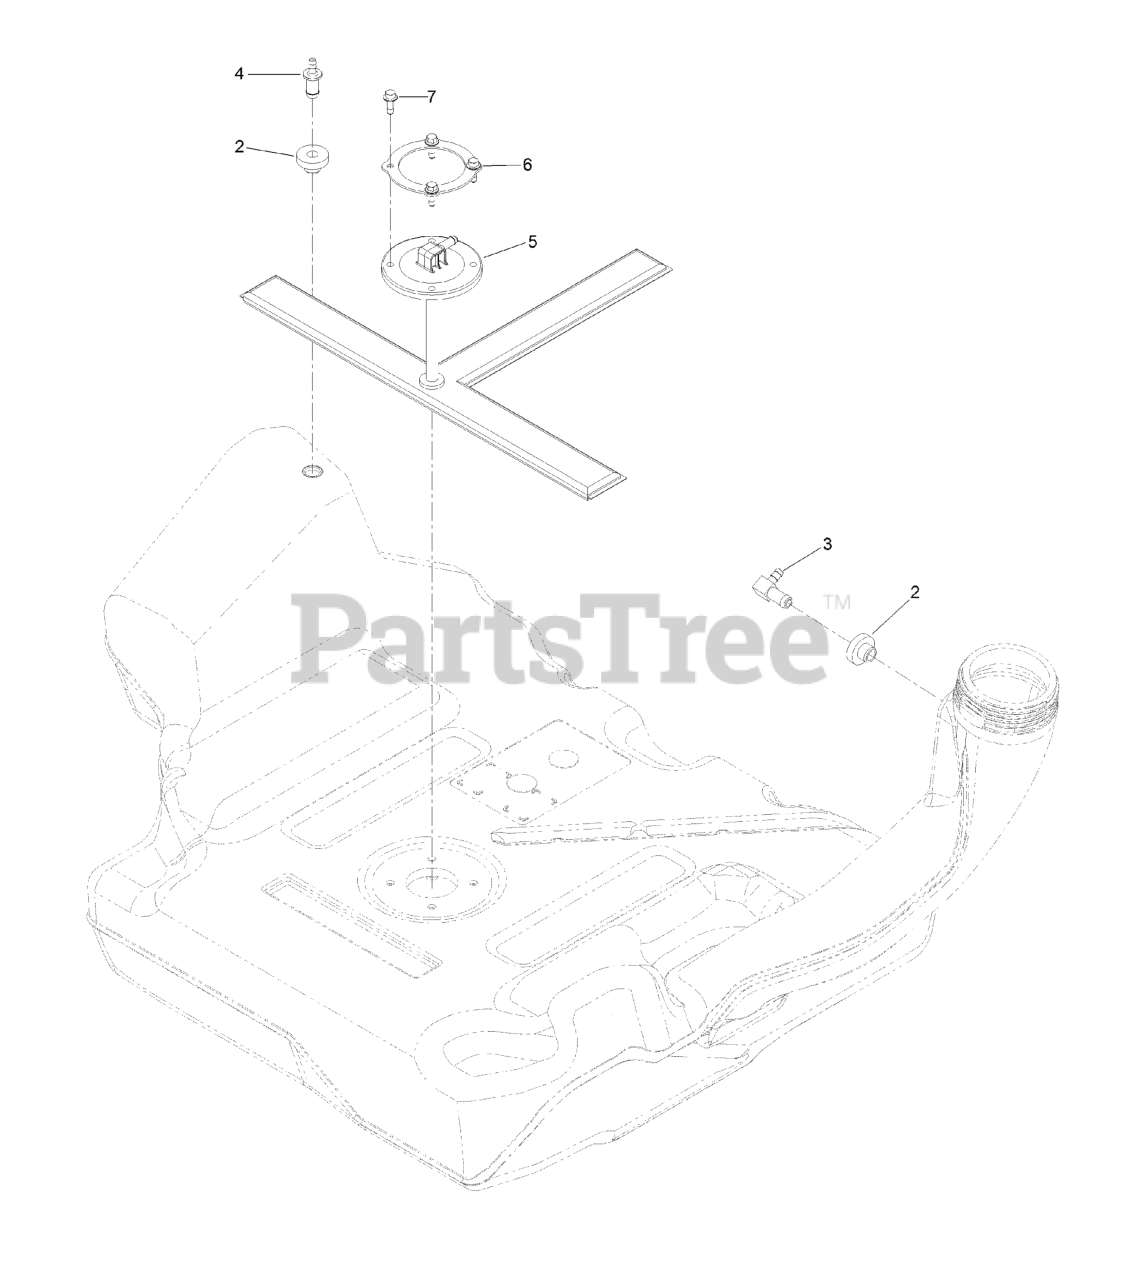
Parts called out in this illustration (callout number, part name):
2	BUSHING
3	FITTING-90 DEG
4	FITTING-ORIFICE, STRAIGHT
5	PICKUP-FUEL
6	RING-RETAINER
